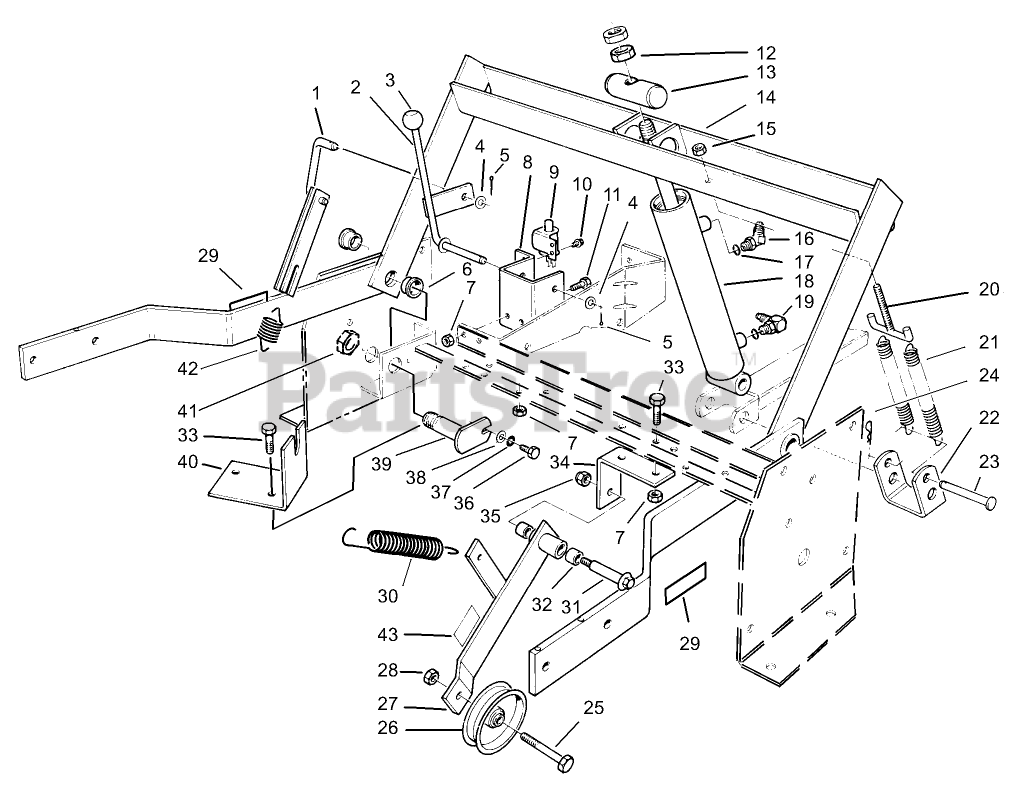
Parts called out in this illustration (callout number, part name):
1	Link-Parking Brake
2	Brake Lever
4	WASHER-FLAT
5	PIN-COTTER
6	BEARING-FLANGE
7	NUT-LOCK, NI
8	Bracket-Parking Brake
9	SWITCH-BRAKE, PARKING
10	SCREW-TAPTITE
11	SCREW-HH
12	NUT-JAM
13	CYL.PIVOT PIN
14	Frame-Lift (Incl. Ref. #6)
15	NUT-HEX, SIDE DEFORM
16	FITTING-45 DEG
17	O-RING
18	CYLINDER - LIFT
19	FITTING-ELBOW, 90
20	T-HOOK W A
21	SPRING_EXTENSION
22	SPRING BRACKET
23	PIN-CLEVIS
24	PIN-HAIR
25	SCREW-HH
26	PULLEY-IDLER
27	Lever-Idler (Incl. Ref. #43)
28	NUT-LOCK, NI
29	Decal-Warning
30	IDLER EXT SPRING
31	BOLT-WHEEL
32	BUSHING
33	SCREW-HH
34	JACKSHFT IDLR BRKT
35	NUT-LOCK
36	SCREW-HH
37	WASHER-LOCK
38	WASHER-FLAT
39	Pin-Pivat
40	TRACT CABLE BRKT
41	NUT-LOCK, NI
42	PARK BRAKE SPRING
43	DECAL-WARNING
